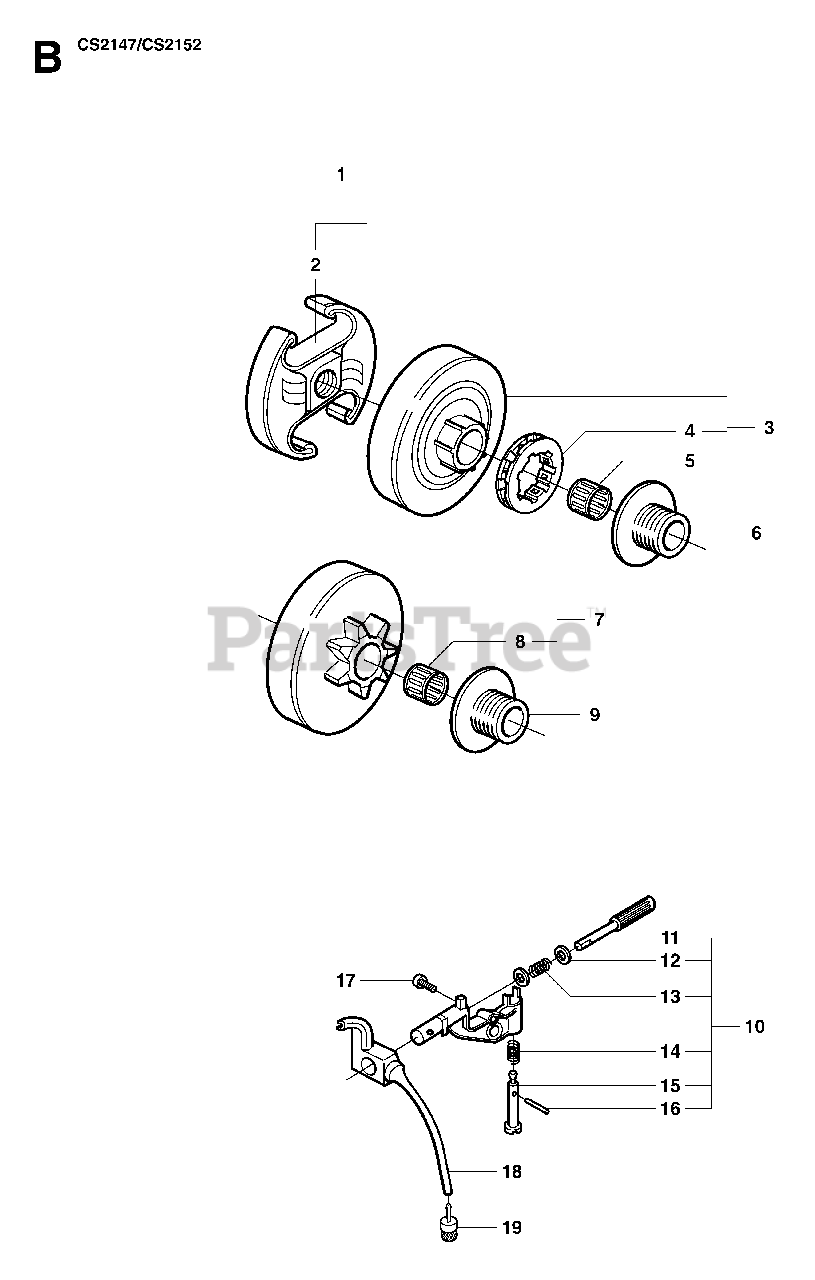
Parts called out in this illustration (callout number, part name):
2	SPRING
3	%CLUTCH DRUM
4	RIM SPROCKET 7T .325
5	NEEDLE BEARING
6	%PINION
7	CLUTCH DRUM
8	NEEDLE BEARING
10	OIL PUMP COMPLETE
11	%PUMP PISTON
19	OIL PLUMMET
